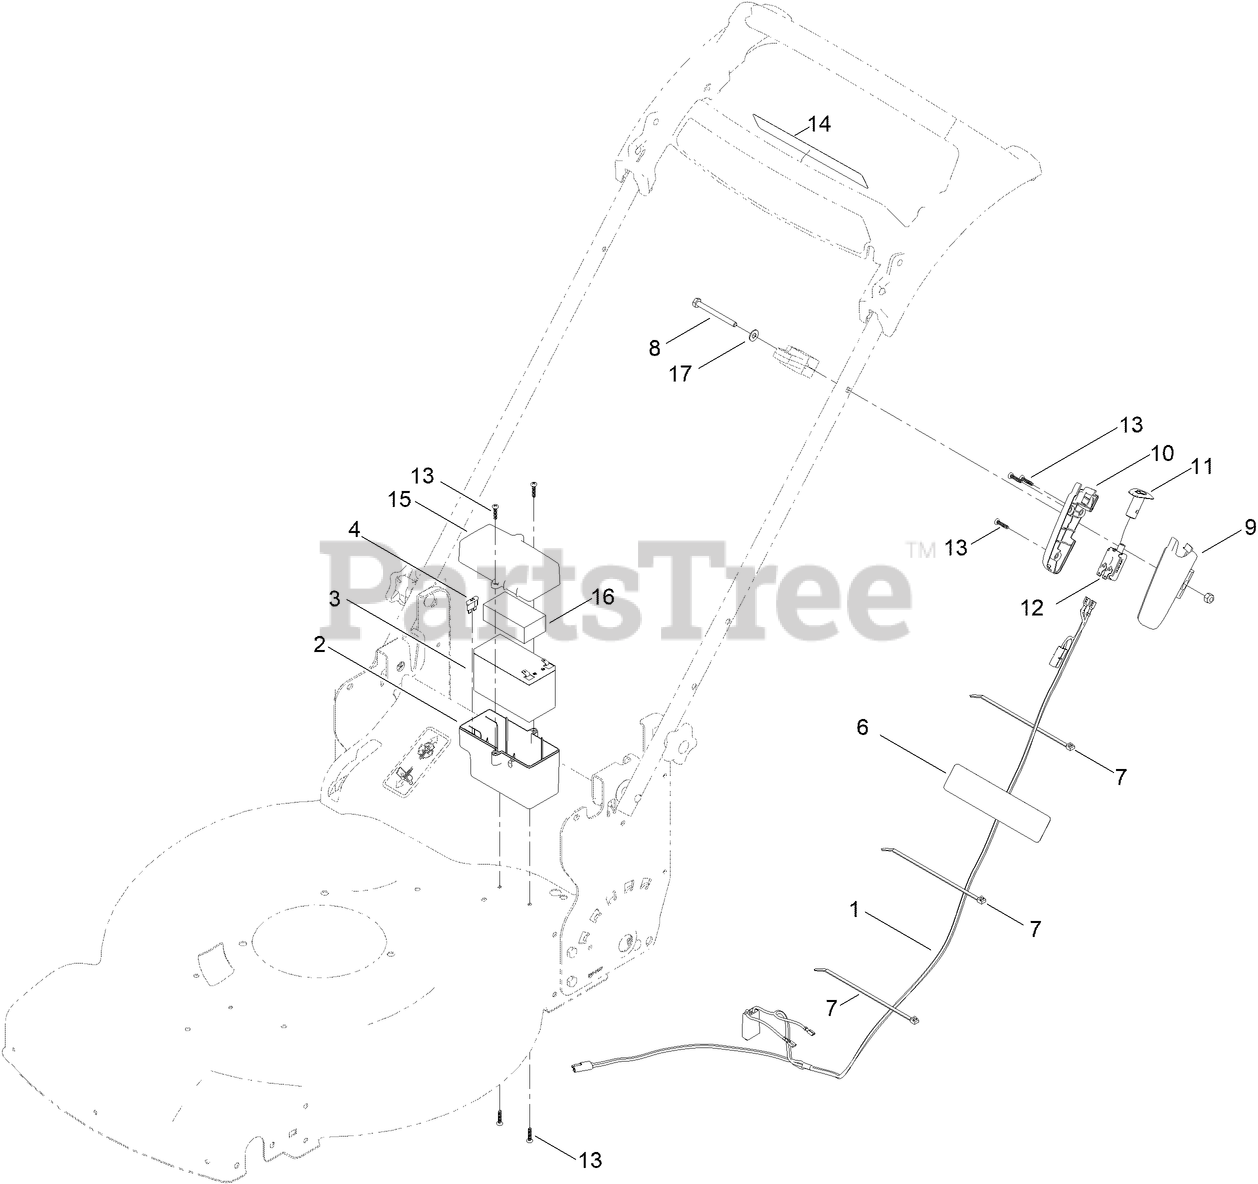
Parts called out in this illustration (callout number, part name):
1	HARNESS-WIRE
2	TRAY-BATTERY
3	BATTERY-NONSPILLABLE, 12 V
4	FUSE-40 AMP
6	DECAL-BATTERY CHARGING
7	TIE-CABLE
8	SCREW-HH
9	HOUSING-SWITCH, LH
10	HOUSING-SWITCH, RH
11	BUTTON-SWITCH
12	SWITCH-PUSH BUTTON
13	SCREW-PPH
14	DECAL-BUTTON, PUSH
15	COVER-BATTERY
16	FOAM-BATTERY, TOP
17	WASHER-FLAT
